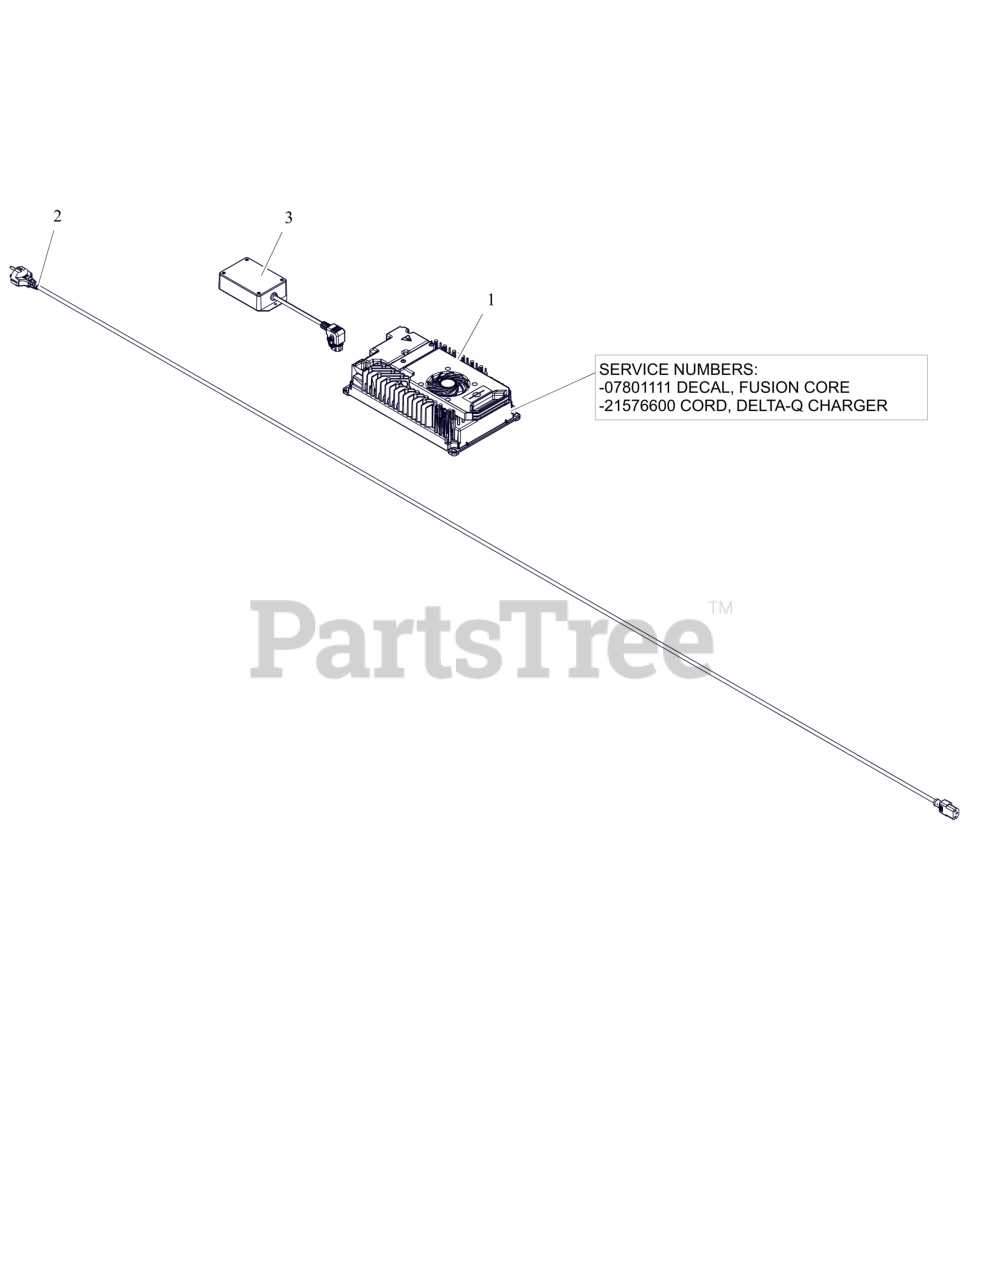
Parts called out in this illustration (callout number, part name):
1	CHARGER, BATTERY DELTA-Q
1	DECAL, FUSION CORE
1	CORD, DELTA-Q CHARGER
2	CORD, POWER EU 220V AC
3	FILTER ,EMI, 120/250V,50-60HZ
